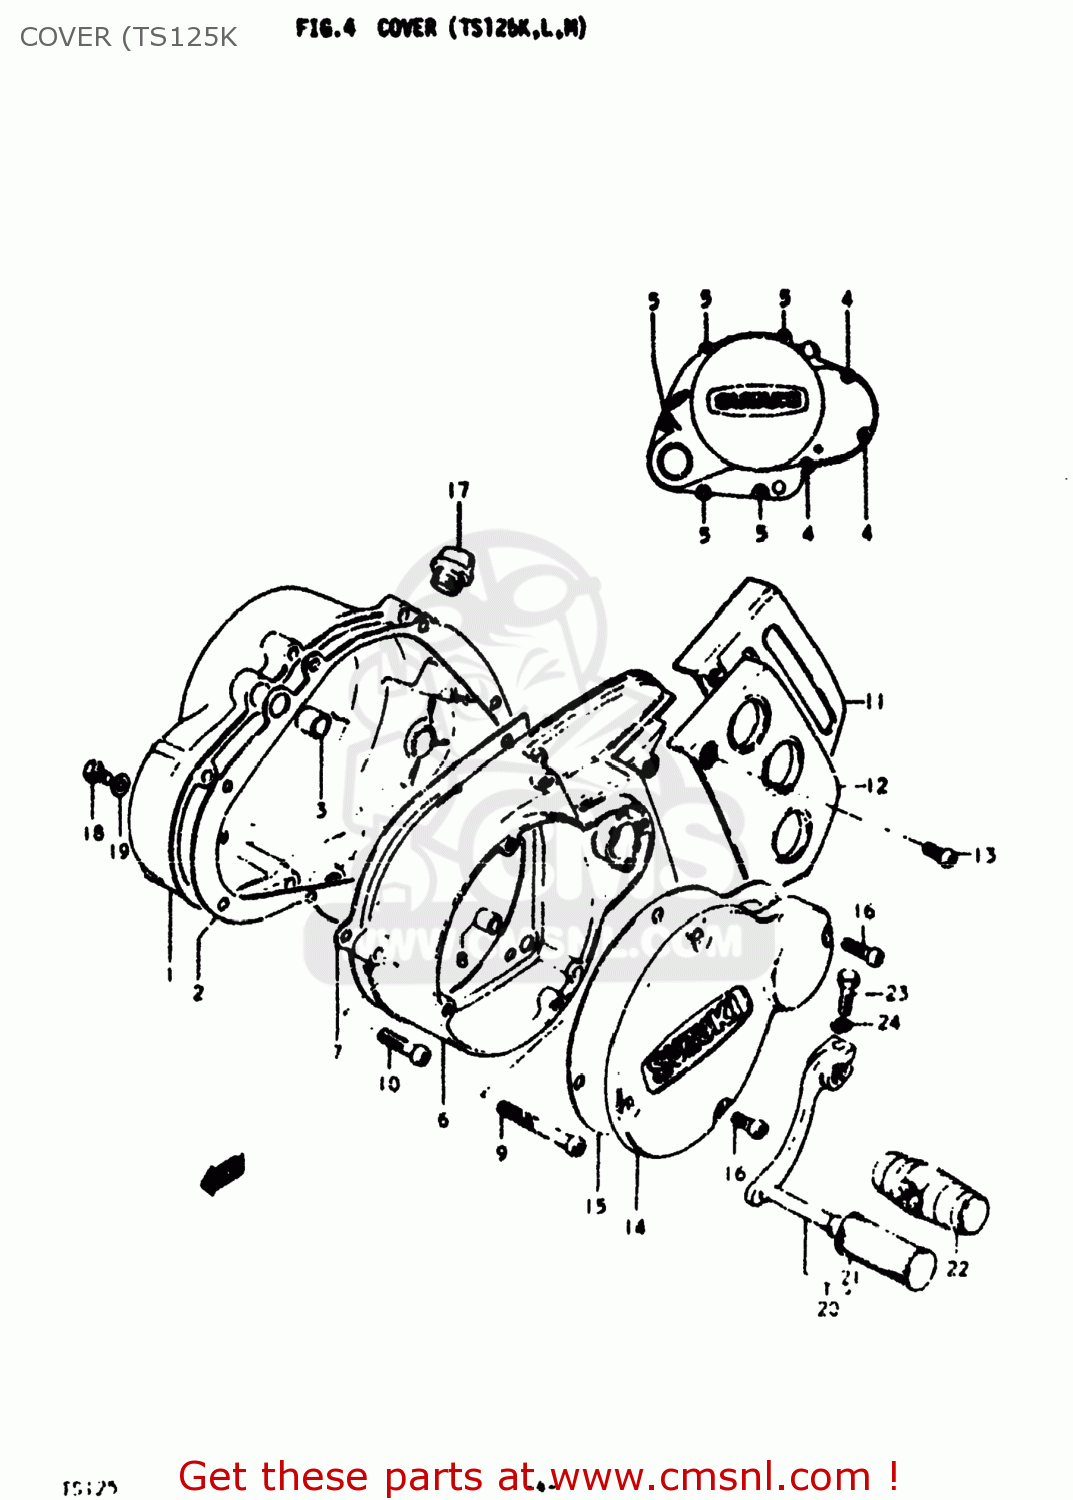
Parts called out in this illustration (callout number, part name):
1	COVER,CLUTCH
2	GASKET,CLUTCH COVER (MCA)
3	PIN
4	SCREW
5	SCREW
6	COVER
7	GASKET,CLUTCH COVER (NAS)
8	PIN
9	SCREW
10	SCREW
11	COVER,SPROCKET
12	COVER,ENGINE SPROCKET
13	SCREW
14	CAP,MAGNETO INSPECTION
15	GASKET,MAGNETO INSPECTION CAP (NAS)
16	SCREW
17	PLUG
18	SCREW(6X10)
19	GASKET(6.2X11X1) (NAS)
20	LEVER ASSY,GEAR SHIFT
21	RUBBER,GEAR SHIFT PEDAL
22	RUBBER,GEAR SHIFT PEDAL
23	BOLT
24	LOCK WASHER
